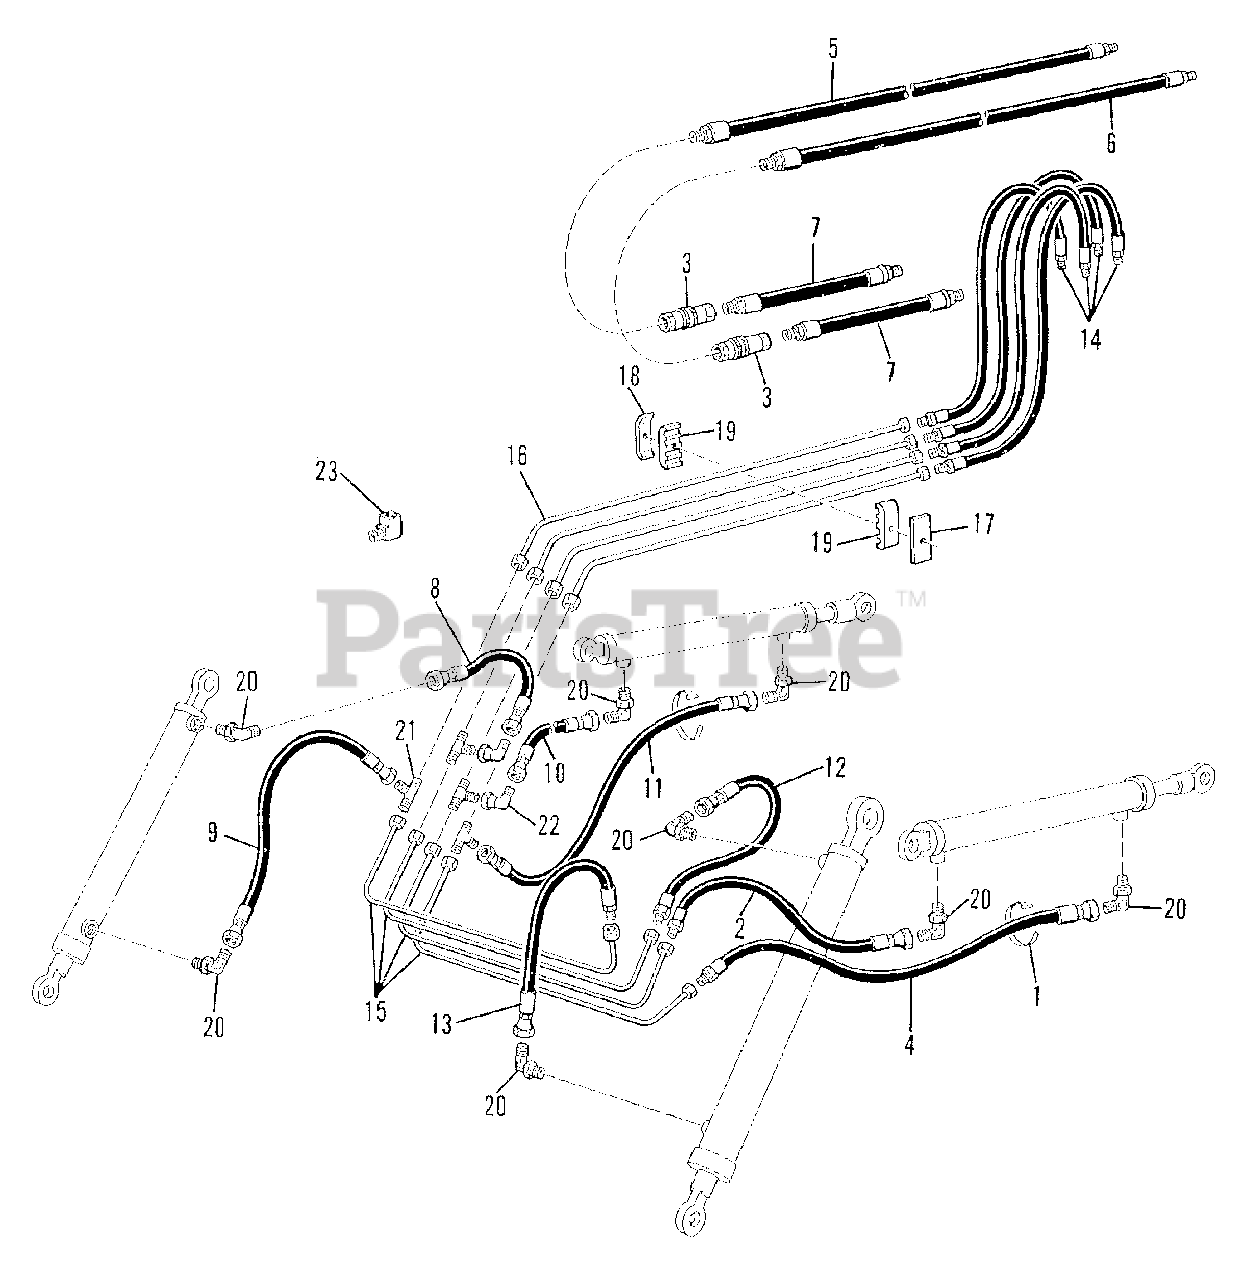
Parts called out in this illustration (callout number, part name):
2	HOSE ASSEMBLY (Left Lift Cylinder at Base End Position)
3	COUPLER, Hose
4	HOSE ASSEMBLY (Left Lift Cylinder at Rod End Position)
5	HOSE ASSEMBLY, Pressure
6	HOSE ASSEMBLY, Return
7	HOSE ASSEMBLY, Valve Inlet & Outlet
8	HOSE ASSEMBLY (Right Tilt Cylinder at Base End Position)
9	HOSE ASSEMBLY (Right Tilt Cylinder at Rod End Position)
10	HOSE ASSEMBLY (Right Lift Cylinder at Base End Position)
11	HOSE ASSEMBLY (Right Lift Cylinder at Base End Position)
12	HOSE ASSEMBLY (Left Tilt cylinder at Base End Position
13	HOSE ASSEMBLY (Left Tilt Cylinder at Rod End Position)
14	HOSE ASSEMBLY, Valve Operating (Prior to S/N 1576)
14	HOSE ASSEMBLY, Valve Operating (Eff. With S/N 1576)
15	TUBE ASSEMBLY, Cross
16	TUBE ASSEMBLY, Side
17	CLAMP, Tube
17	CAPSCREW, 1/4NC x 2
17	LOCKWASHER, 1/4
18	BRACKET, Clamp
19	CUSHION, Clamp
20	ELBOW, Hose Adapter, 3/8 Tube O.D.
20	O-RING, 15/32 I.D.
21	TEE, 3/8 Tube O.D.
22	ELBOW, Swivel Adapter, 3/8 Tube O.D.
23	ELBOW, Street, 90 Degrees
